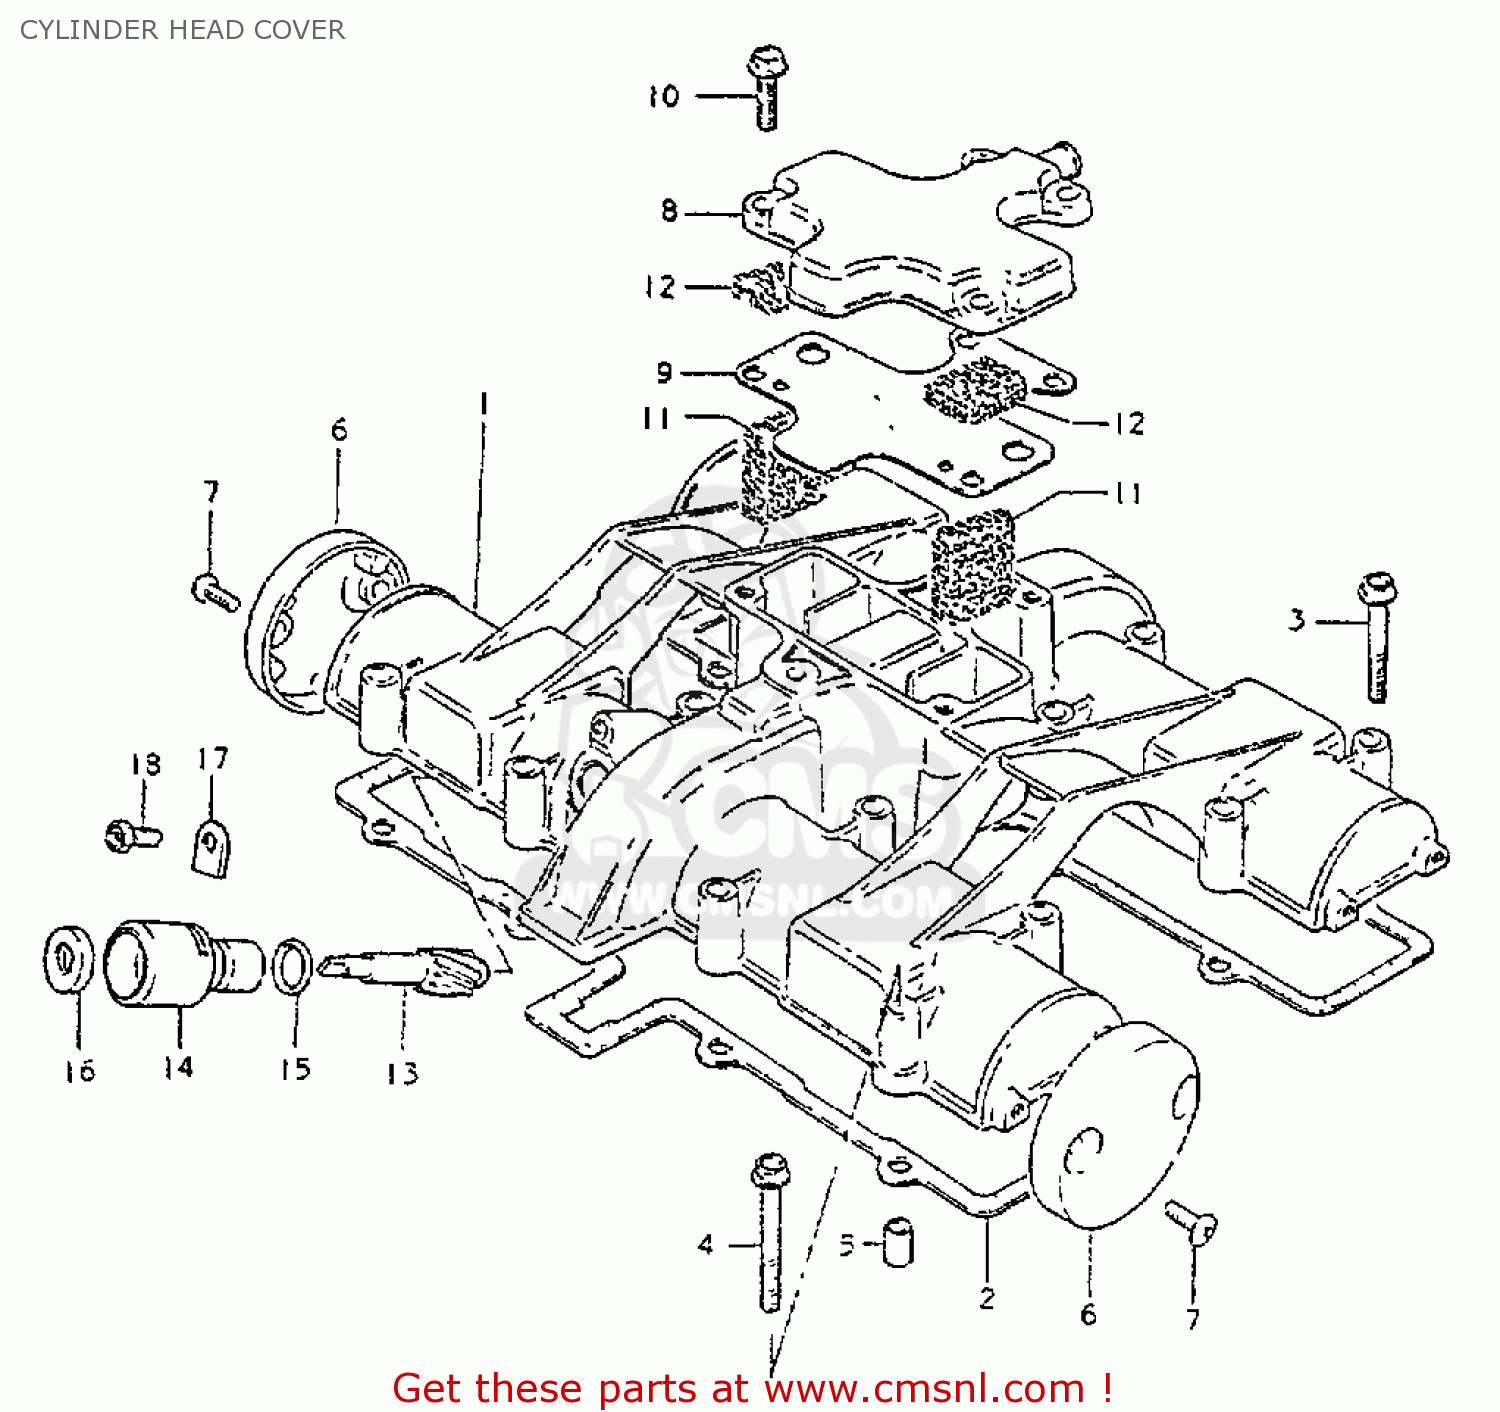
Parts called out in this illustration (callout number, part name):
1	COVER,CYLINDER HEAD
2	GASKET,CYLINDER HEAD COVER (MCA)
3	BOLT
4	BOLT,UNDER
5	PIN(6.2X8X11)
6	CAP,CYLINDER HEAD COVER
7	SCREW 5X12
8	COVER,BREATHER
9	GASKET (MCA)
10	BOLT,REAR
11	COVER,BREATHER
12	SEPARATOR,OIL BREATHER
13	GEAR,TACHOMETER DRIVEN
14	SLEEVE,TACHOMETER DRIVE
15	SEAL,TACHOMETER DRIVEN
16	SEAL,OIL(5X12X8)
17	PLATE,TACH DRIVE GEAR SLEEVE
18	SCREW(5X12)
